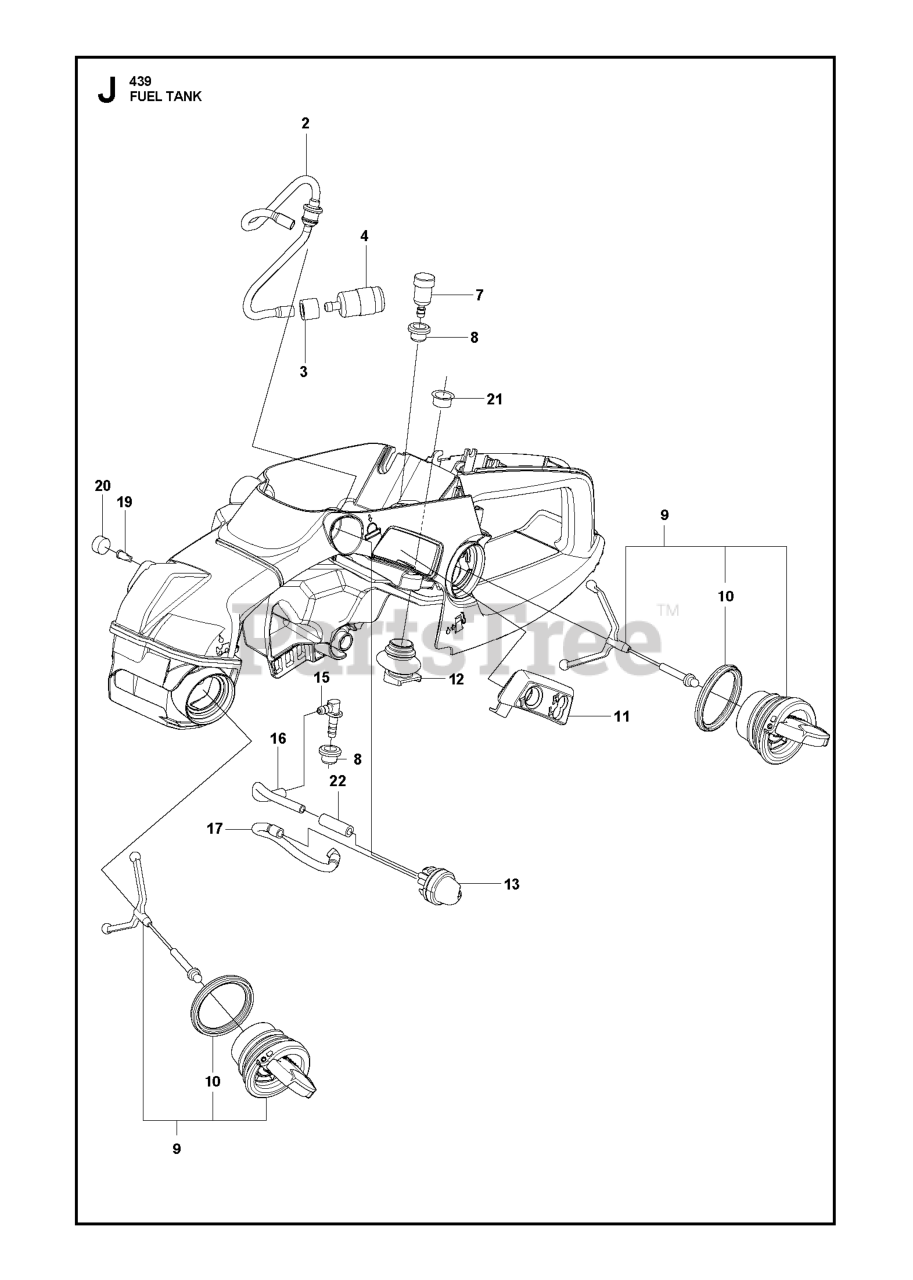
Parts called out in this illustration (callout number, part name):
2	FUEL HOSE ASSY ROHS2
2	HOSES
9	TANK CAP ASSY
10	GASKET TANK CAP
11	GROMMET CARB 439
13	PRIMARY BTN
16	FUEL HOSE L=90 ROHS2
17	FUEL HOSE L=115 ROHS2
19	AIR CONTROL BREATHER
20	BREATHER SEAL
